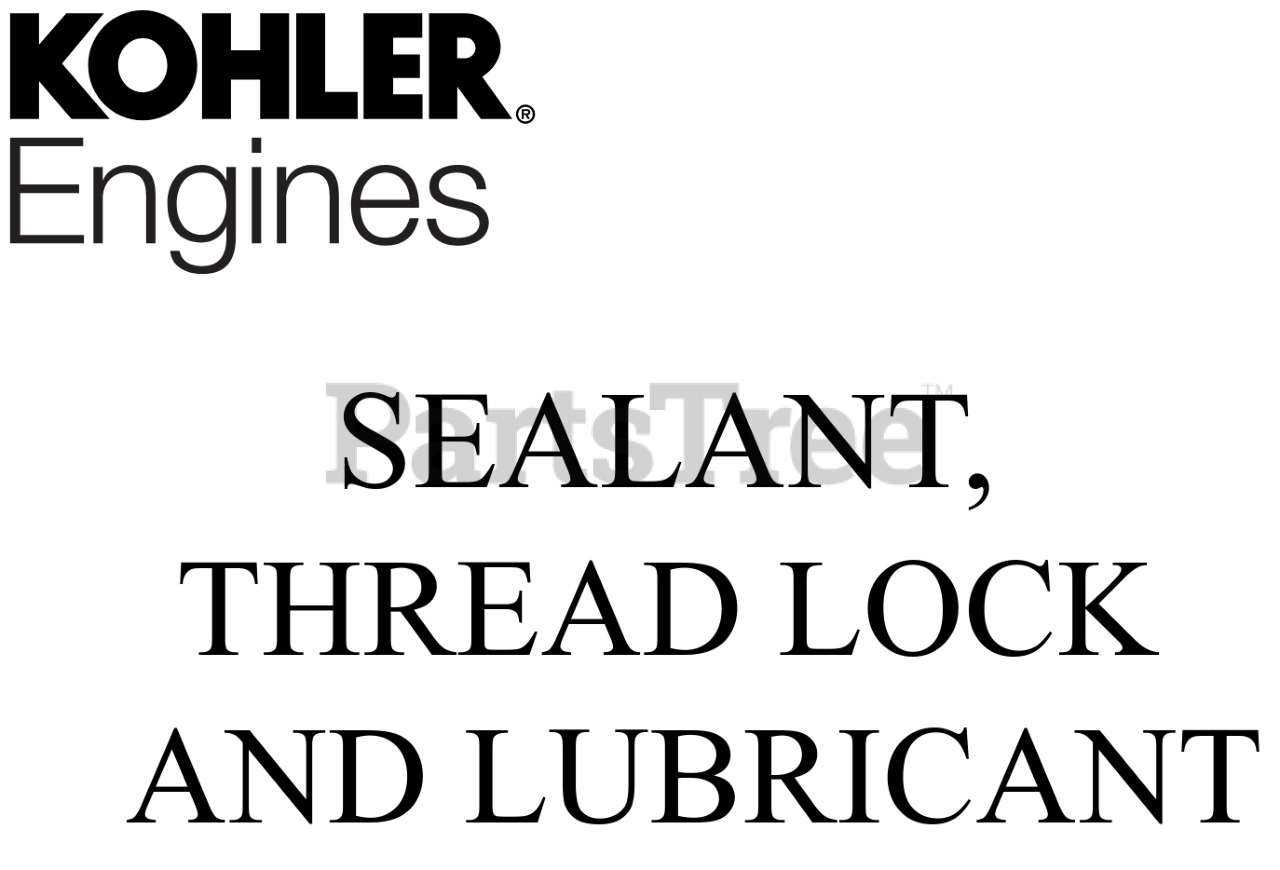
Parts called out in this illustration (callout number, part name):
NI	QUART OF OIL - SAE30
NI	QUART OF OIL - 10W30-USE 25 357 65-S
NI	LUBRICANT, GREASE (SPLINE)
NI	LUBRICANT, CAMSHAFT
NI	20W50 OIL (QUART)-USE 25 357 68-S
NI	SEALANT(LOCTITE 620)-(#2559711S)
NI	SEALANT(LOCTITE 222 RETAIN CMPND 0.5ML)
NI	SEALANT(LOCTITE INSTANT GASKET 4 OZ)
NI	LUBRICANT, BENDIX STARTR
